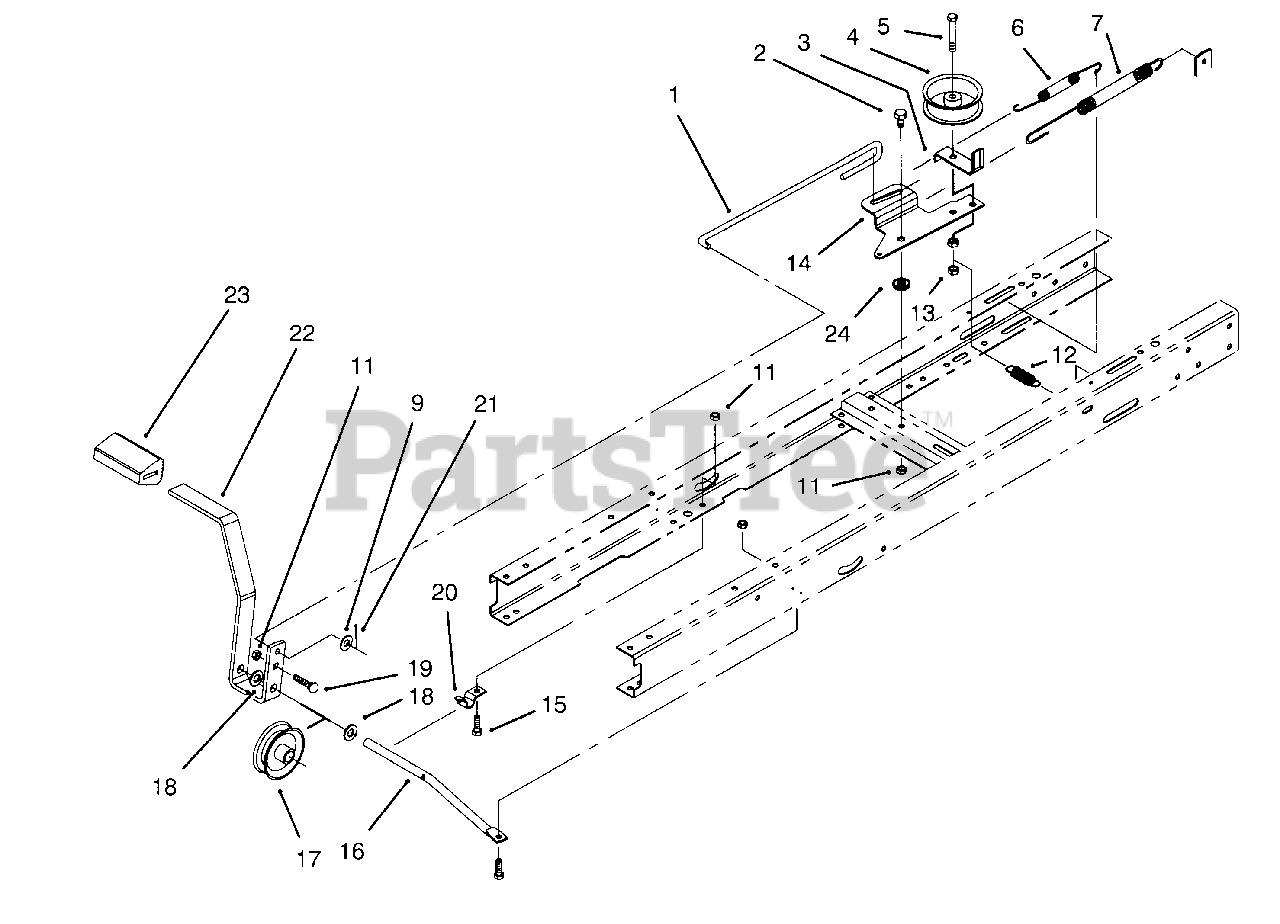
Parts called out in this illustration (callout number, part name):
1	Rod-Clutch/Brake
2	Bolt-Shoulder
3	Guide-Idler Belt
4	Pulley-Flat Idler
5	Screw-Hex Hd. Cap
6	Spring-Pedal Return
7	Spring-Brake
9	Washer-Flat
11	Nut-Lock
12	Spring-Extension
13	Nut-Lock
14	Arm-Idler
15	Screw-Hex Hd. Cap
16	Rod-Pedal Pivot
17	Pulley-Cable
18	Washer-Flat
19	Bolt-Carriage
20	Clamp-Shift Pivot
21	Pin-Cotter
22	Pedal-Clutch/Brake
23	Pad-Pedal
24	Washer-Fender
